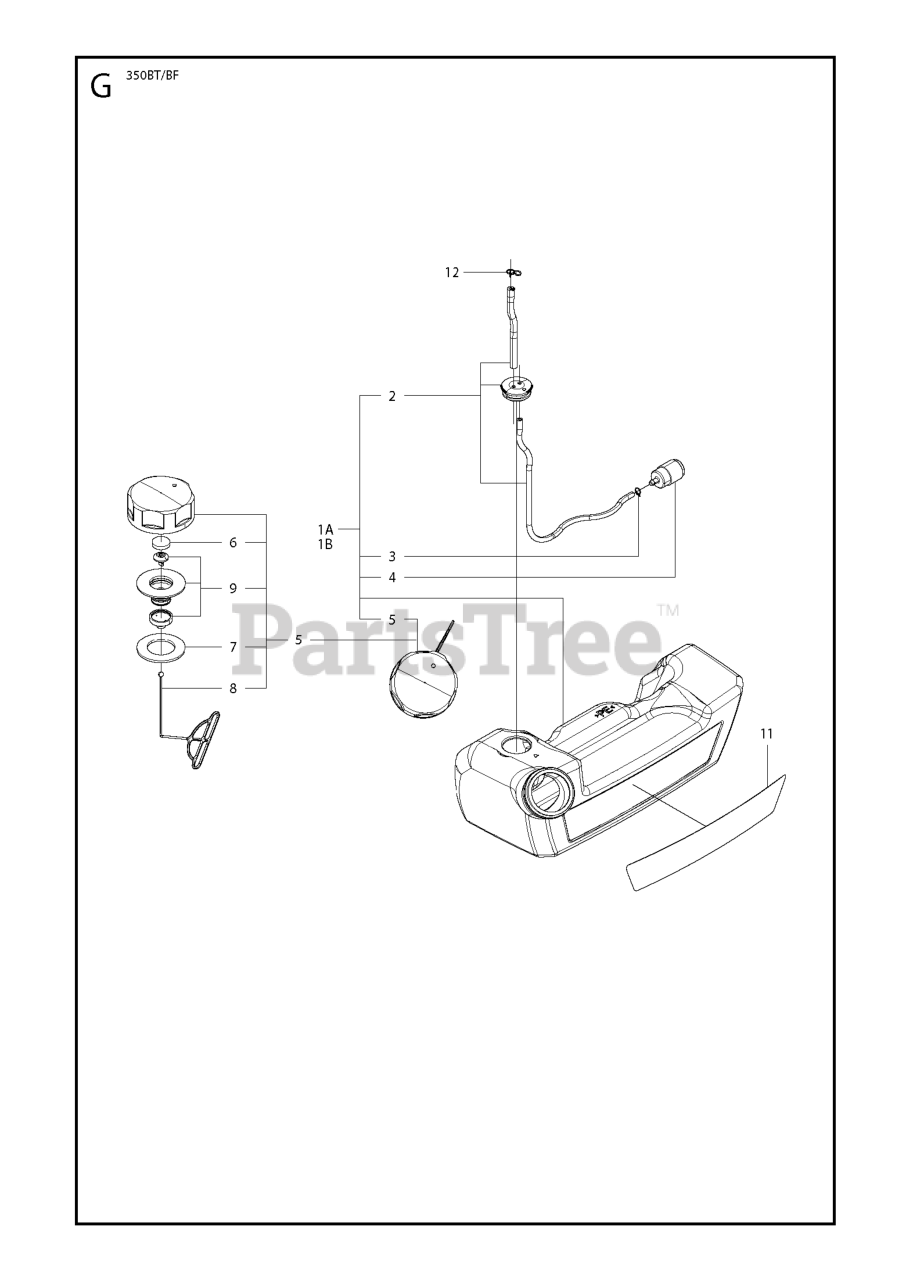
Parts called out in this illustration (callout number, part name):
1A	TANK ASSY FOR EU
1B	FUEL TANK ASSY
2	Fuel Hoses
2	Pipes
4	RP FUEL FILTER
5	ASSY FUEL CAP
